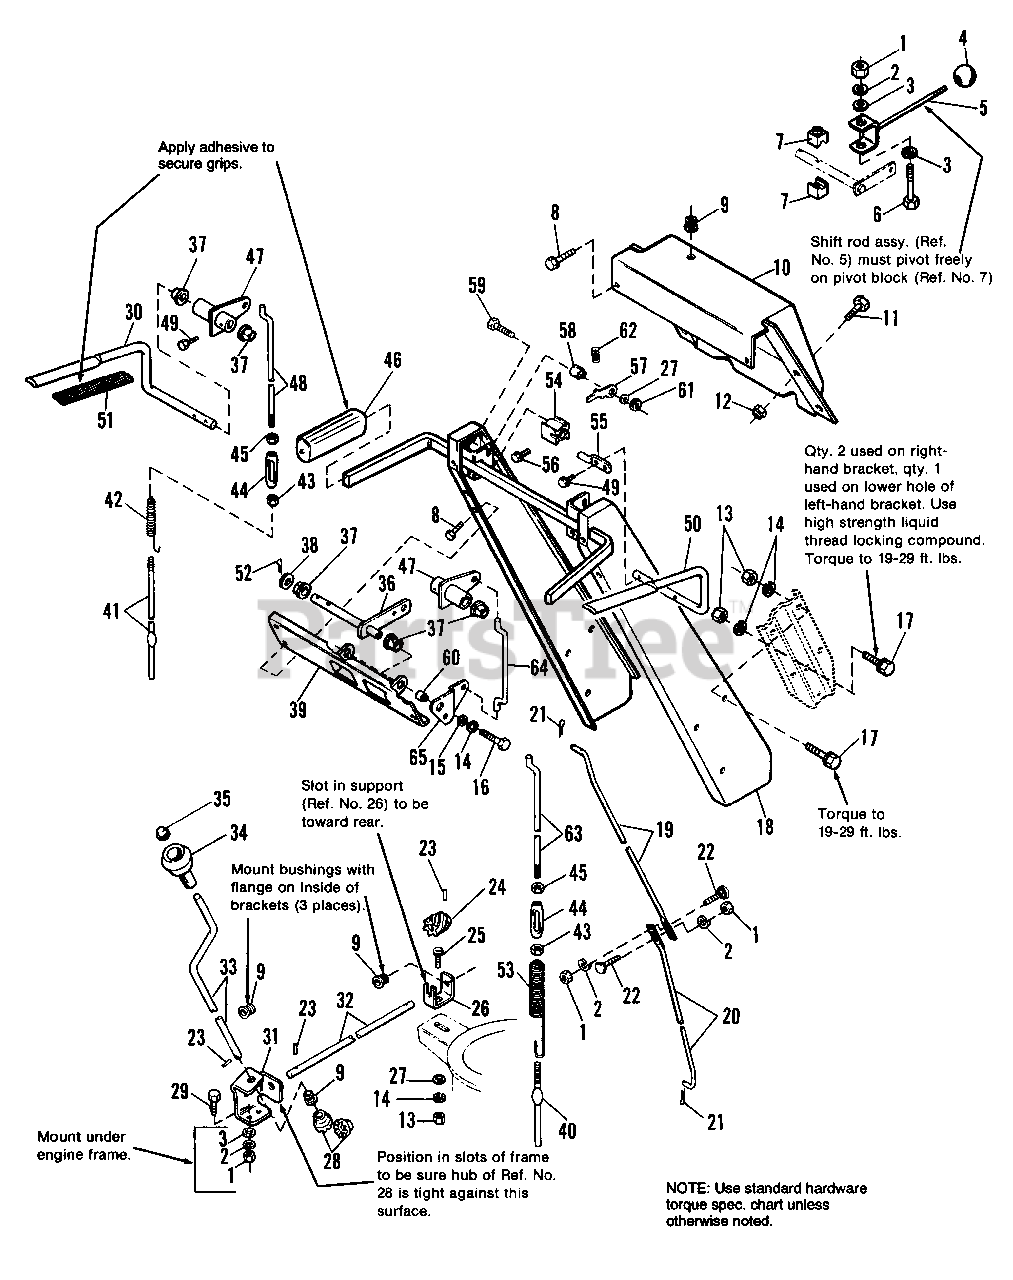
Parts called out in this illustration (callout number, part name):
1	NUT, Hex, 1/4-20
2	LOCKWASHER, 1/4
3	WASHER, Flat, 9/32
5	SHIFT ROD ASSY.
6	CAPSCREW, Hex Hd., 1/4-20 x 2-1/4
7	BLOCK, Pivot
8	SCREW, Taptite, 1/4-20 x 1/2
9	BUSHING, Plastic
10	DASH, Handle
11	CAPSCREW, Washer Hd.,1/4-20 x 3/4
12	NUT, Nylon Lock, 1/4-20
13	NUT, Hex, 5/16-18
14	LOCKWASHER, 5/16
15	WASHER, Plain, 5/16 x 1
16	CAPSCREW, Hex Hd., 5/16-18 x 1-3/4
17	CAPSCREW, Whizlock, 5/16-18 x 3/4
18	HANDLE ASSY.
19	ROD, Shift-Upper
20	ROD, Shift-Lower
21	PIN Cotter
22	BOLT, Carriage, 1/4-20 x 3/4
23	PIN, Roll, 1/8 x 3/4
24	WORM, Chute
25	BOLT, Carriage, 5/16-18 x 3/4
26	SUPPORT, Worm
27	WASHER, Flat, 11/32
28	GEAR, Universal
29	CAPSCREW, Hex Hd., 1/4-20 x 3/4
30	HANDLE, Clutch, L.H.
31	SUPPORT, Universal Gear
32	ROD, Chute Worm
33	ROD, Chute Control
34	KNOB, Spinner
35	PALNUT
36	PIVOT ROD ASSY.
37	BUSHING, Plastic
38	WASHER
39	BRACKET, Shift Control
40	ROD, Clutch-Lower, Auger
41	ROD, Clutch-Lower, Traction
43	NUT, Hex, #10-24, R.H.
45	NUT, Hex, #10-24, L.H.
46	GRIP, Handle Bar
47	CLUTCH LEVER ASSY.
48	ROD, Clutch-Upper
49	SCREW, Taptite, #12-24 x 1
50	HANDLE, Clutch R.H.
51	GRIP, Clutch
52	PIN, Cotter, 1/8 x 1
53	SPRING, Extension
54	GUIDE, Control
55	ROD, Control
56	SCREW, Taptite, #10-32 x 1.00
57	LATCH, Control
58	SPACER, Special
59	CAPSCREW, Hex Hd., 5/16-18 x 1-1/2
61	NUT, Hex Lock, 5/16-18
62	SPRING
63	ROD, Upper Clutch, Auger
64	ROD, Clutch
65	LEVER, Clutch
